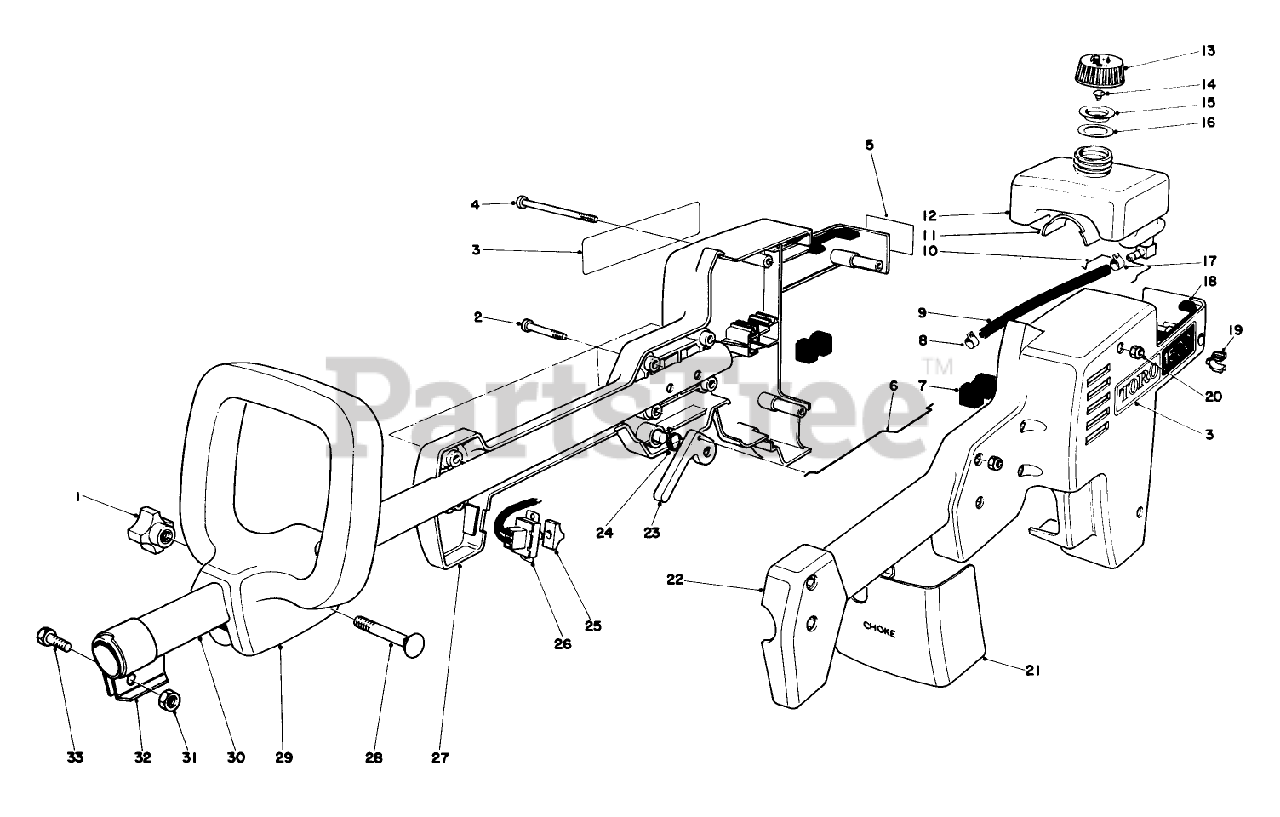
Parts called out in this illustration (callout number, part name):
2	SCREW-PPH
4	SCREW-PPH
17	CLAMP-HOSE
20	NUT-LOCK, NI
24	TORSION SPRING
26	SWITCH
31	NUT-LOCK, NI
33	SCREW-HH
